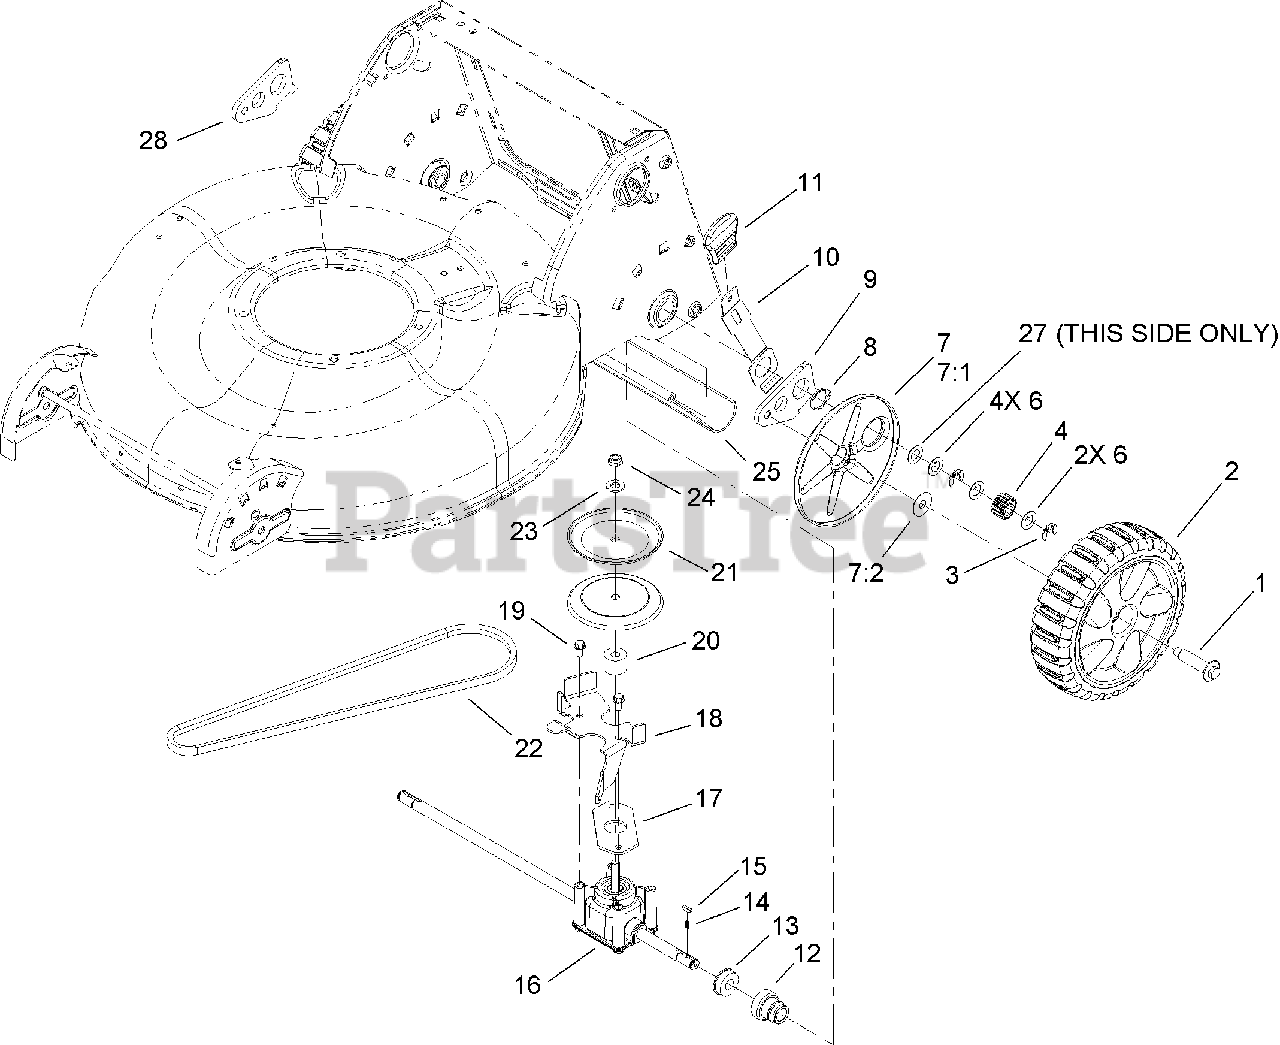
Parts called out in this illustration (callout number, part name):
1	BOLT-SHOULDER
2	REAR WHEEL ASM
3	KLIPRING-LOCKING
4	Gear-Pinion, 15t
6	Washer-Thrust
7	WHEEL COVER ASM
7:1	COVER-WHEEL
7:2	WASHER-STEPPED
8	RING-RETAINING
9	ARM-REAR PIVOT, LH
10	ARM-SPRING, REAR
11	KNOB-LEVER, HOC
12	RETAINER-BEARING, HOC
13	BEARING-BALL
14	SPRING-COMPRESSION
16	TRANSMISSION ASM
17	GASKET-GEARBOX
18	BRACKET-TRANSMISSION
19	SCREW-HWH
21	PULLEY-HALF
23	WASHER-FLAT
24	NUT-LOCK
25	SHIELD-TRAILING
28	ARM-REAR PIVOT, RH
